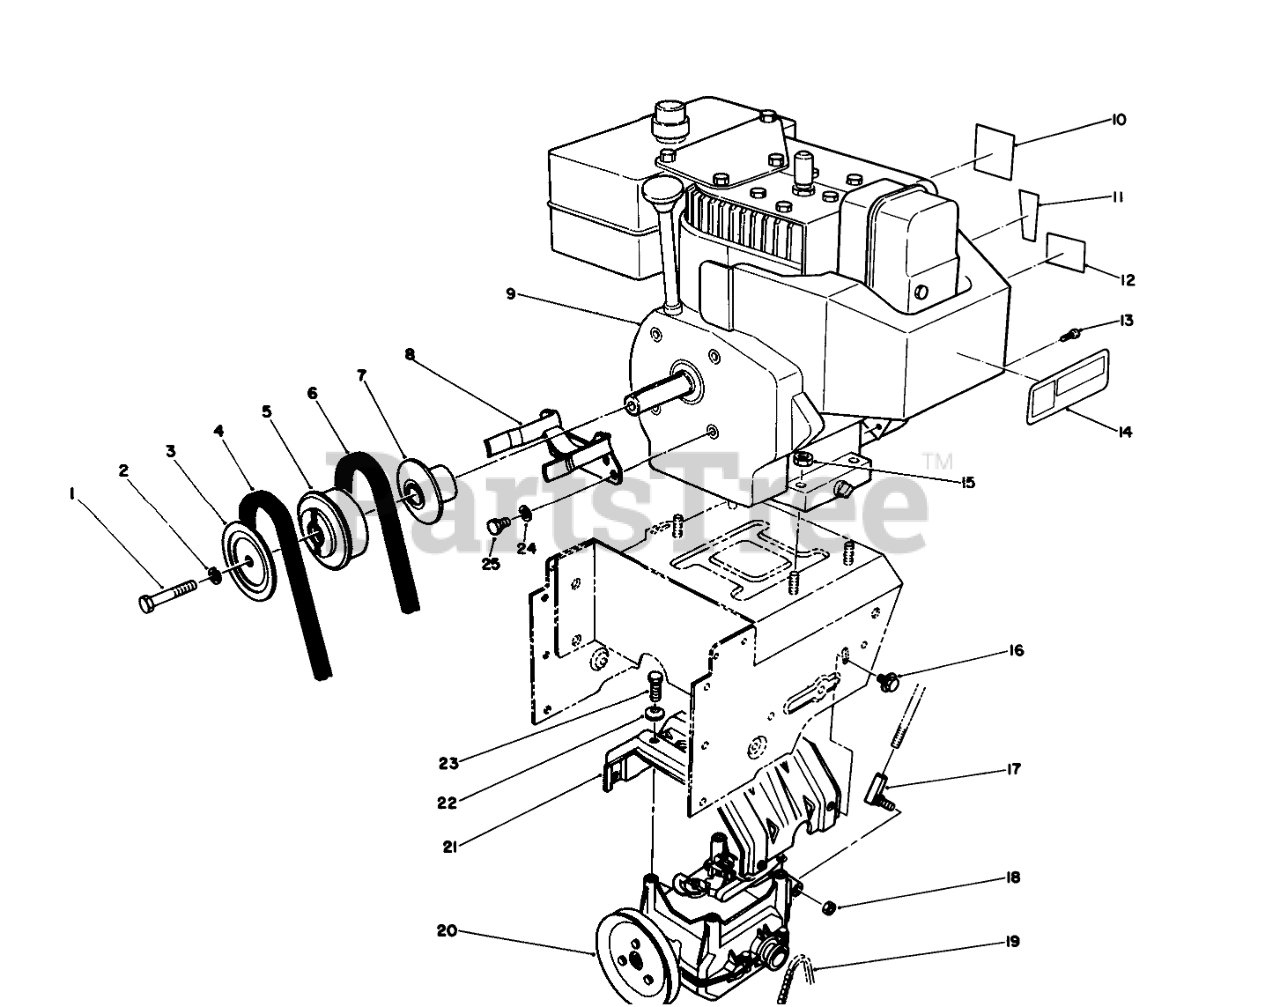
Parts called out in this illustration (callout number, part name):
1	SCREW-HH
2	WASHER-LOCK
3	SHEAVE-HALF, IMPELLER
4	V-BELT
5	PULLEY-ENGINE, CENTER
6	V-BELT-TRACTION
7	SHEAVE-HALF, TRACTION
8	Guide-Belt
10	DECAL-PRIMER
11	DECAL-THROTTLE
12	DECAL-CHOKE
13	SCREW-HWH
14	DECAL-HOT SURFACE, WARNING
15	NUT-HF
16	SCREW-HHF
17	JOINT-BALL
18	NUT-LOCK, NI
19	CHAIN
20	TRACTION GEARCASE ASM
21	Frame-Transmission
22	WASHER-SPRING
23	SCREW-HWHTF
24	WASHER-LOCK
25	SCREW-HH
